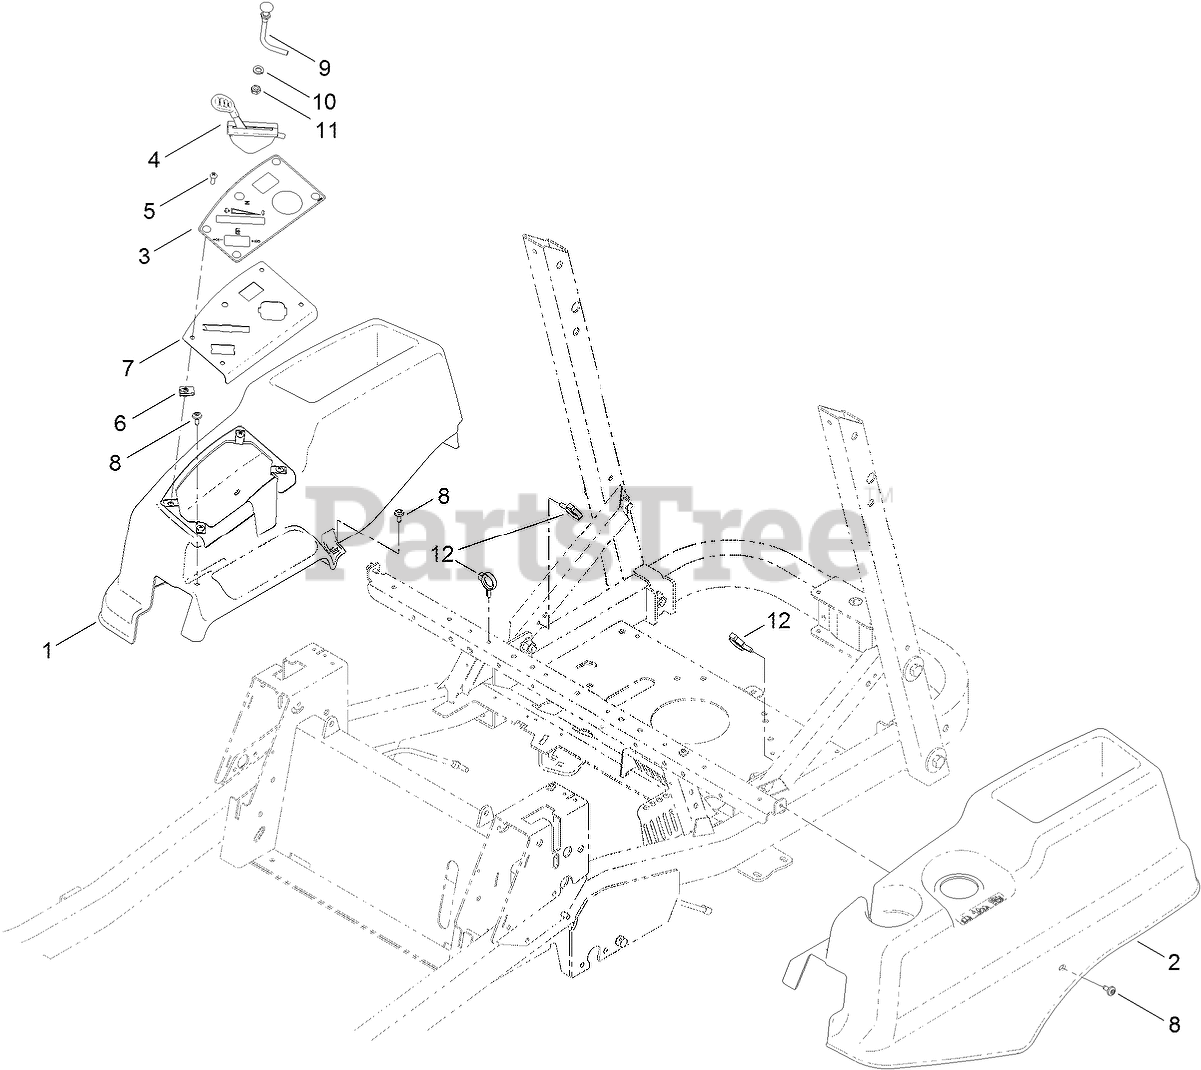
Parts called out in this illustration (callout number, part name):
1	POD-RH
2	POD-LH
3	DECAL-PANEL, CONTROL
4	CABLE-THROTTLE
5	SCREW-PRH
7	PANEL-CONTROL
8	SCREW-SHOULDER
9	CABLE-CHOKE
10	WASHER-LOCK
11	NUT-HJ
12	CLAMP-HOSE
